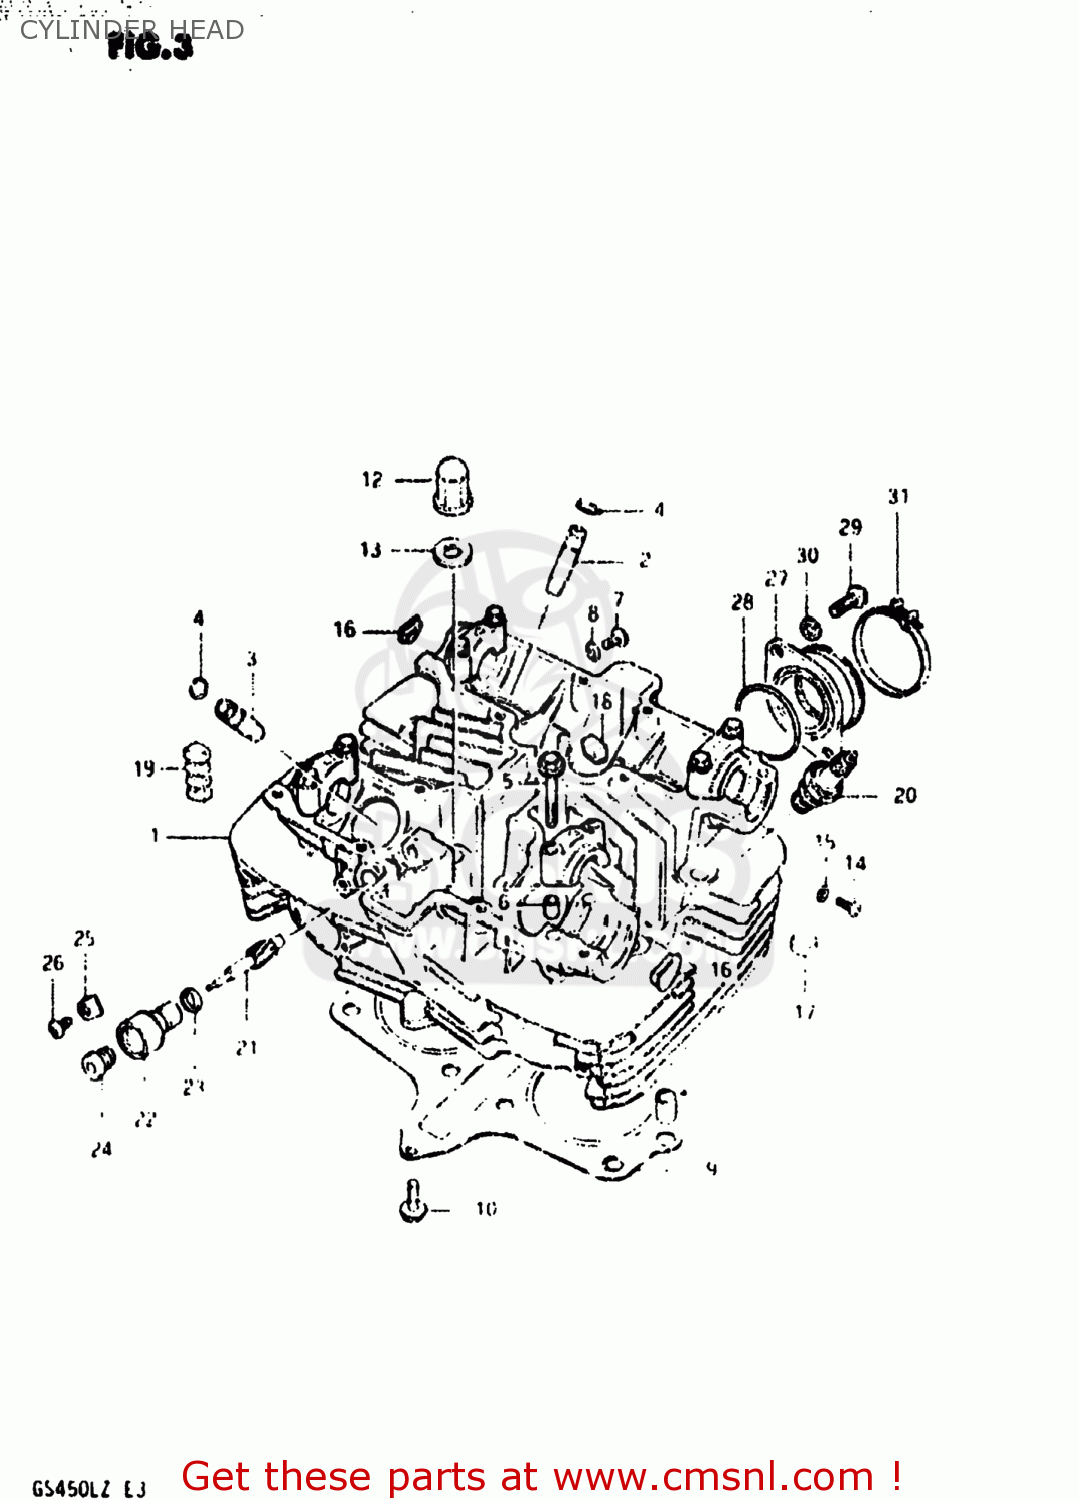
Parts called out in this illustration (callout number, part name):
1	HEAD ASSEMBLY,CYLINDER
2	GUIDE,INTAKE VALVE
3	GUIDE,EXHAUST VALVE
4	RING,SNAP
5	BOLT(6X39)
6	PIN(6.2X8X11)
7	BOLT
8	GASKET (NAS)
9	GASKET,CYLINDER HEAD (MCA)
10	BOLT
11	PIN
12	NUT
13	GASKET (NAS)
14	SCREW
15	GASKET(5.3X9.3X1.2) (NAS)
16	PLUG
17	PAD,CYLINDER HEAD
18	PAD
19	PAD,CYLINDER
20	SPARK PLUG
21	GEAR,TACHOMETER DRIVEN
22	SLEEVE,TACHOMETER DRIVE
23	SEAL,TACHOMETER DRIVEN
24	SEAL,OIL(5X12X8)
25	PLATE,TACH DRIVE GEAR SLEEVE
26	SCREW(5X12)
27	PIPE,INTAKE
28	O-RING (D:2.4 ID:39.7)
29	SCREW
30	LOCK WASHER
31	CLAMP
